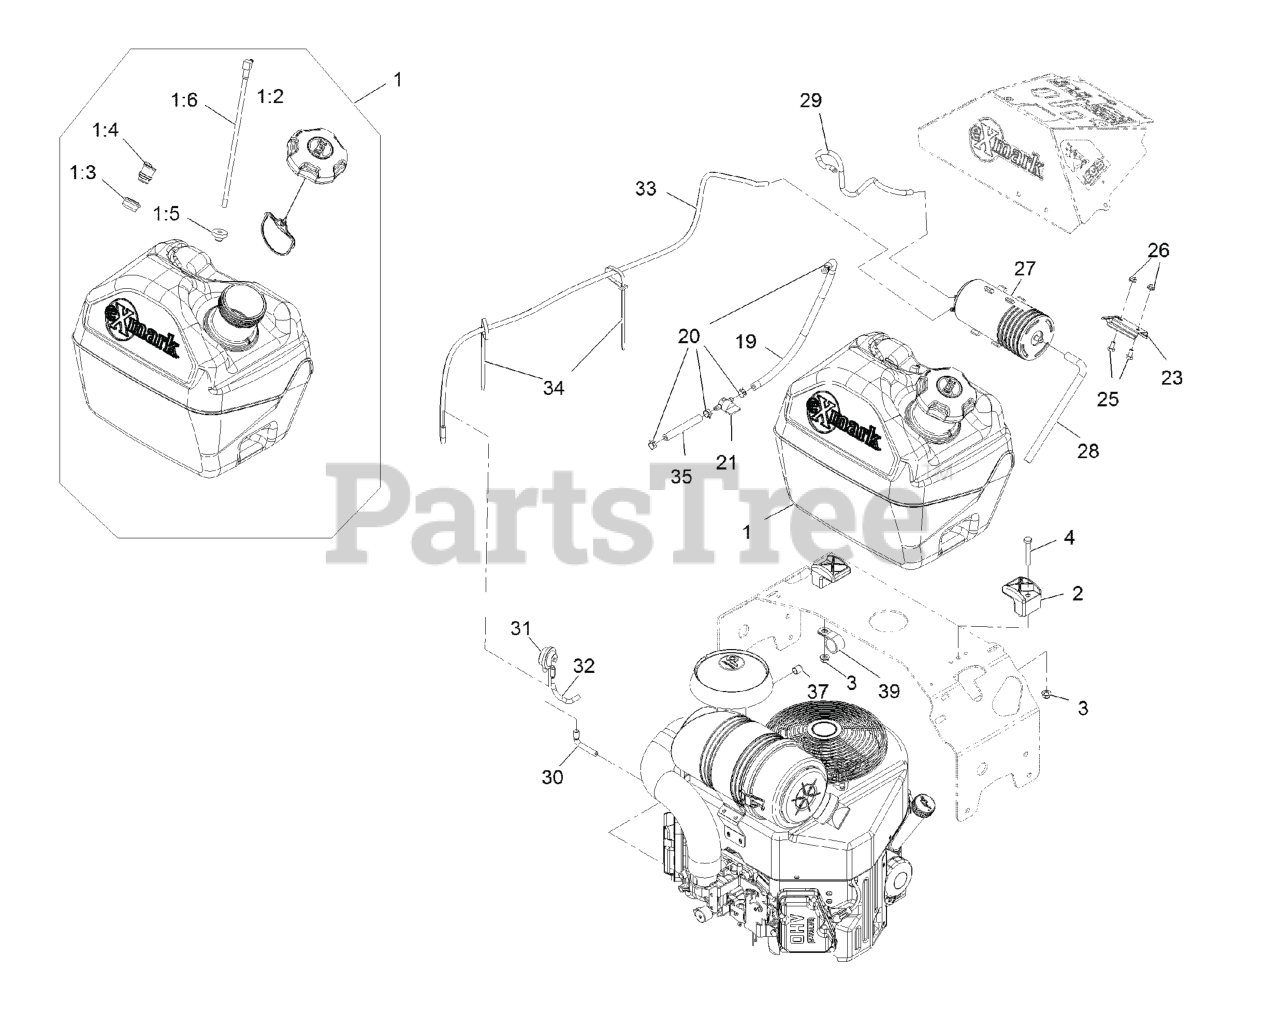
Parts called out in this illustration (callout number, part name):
1	ASM, FUEL TANK 5 GAL
1:2	CAP-FUEL, RATCHETING
1:3	GROMMET
1:4	VALVE-VENT, FUEL
1:5	BUSHING
3	NUT-HF, NI
4	SCREW-HH
19	HOSE-FUEL
20	CLAMP-HOSE
21	VALVE-FUEL
23	BRACKET-CANISTER, CARBON
25	SCREW-HH
27	CANISTER-CARBON, 800CC
28	HOSE-VENT, CANISTER
29	HOSE-EMISSIONS
30	HOSE-VENT, FORMED
31	VALVE-CONTROL, VACUUM
32	HOSE-VENT, FORMED
33	HOSE-VENT, FORMED
34	TIE-PLASTIC
35	HOSE-FUEL
37	PLUG-PORT
39	CLIP-LOOM
